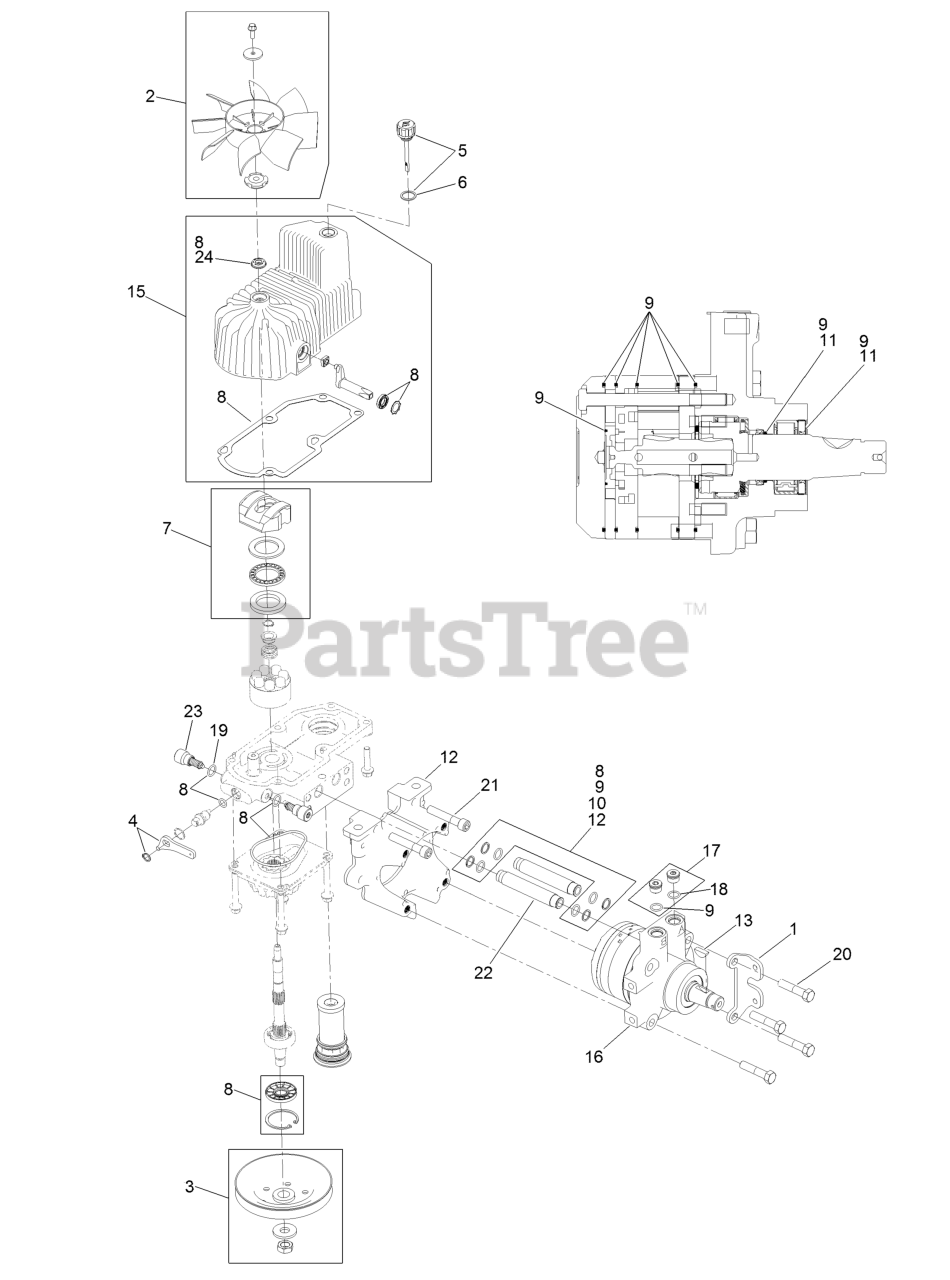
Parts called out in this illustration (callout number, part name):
1	MOUNT-SHOE, HORSE
2	FAN KIT
3	PULLEY KIT
4	HANDLE-BYPASS VALVE, HYDRO
5	DIPSTICK-HYDRO W/GASKET
6	GASKET-DIPSTICK, HYDRO
7	SWASH BLOCK KIT
8	PUMP SEAL KIT
9	MOTOR SEAL KIT
10	TUBE SEAL KIT
11	OUTPUT SHAFT SEAL KIT
12	NOSE CUP-UHT
13	KEY-WOODRUFF
15	HOUSING-HYDRO, RH
16	MOTOR-HYDRAULIC RH 240CC
17	MAGNETIC PLUGS SERVICE KIT
19	O-RING-CHECK VALVE
20	SCREW HH
21	SCREW-HSH
22	HYDRAULIC TUBE KIT
23	SHOCK VALVE, 12CC HYDRO
24	SEAL-FAN DRIVE
